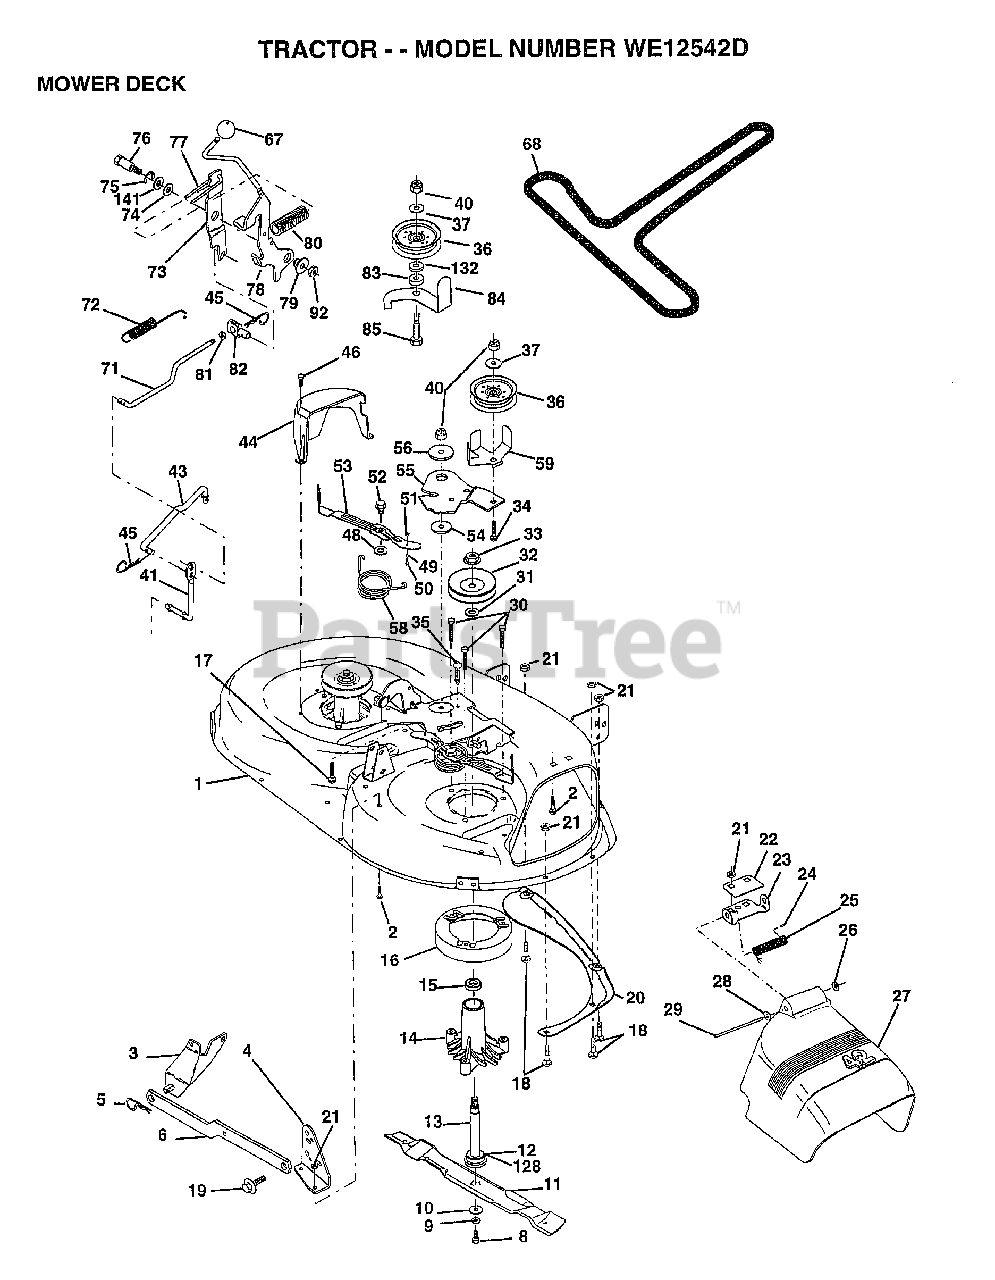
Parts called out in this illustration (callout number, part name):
1	"HOUSING ASSY.42"""
2	BOLT
3	BRKT ASM SWAY BAR
4	BRKT DECK SW BAR
8	BLADE BOLT
10	WASHER.HARD.BLADE
11	"BLADE.42"" HIPERF"
12	BEARING.BALL
14	HSG ASM MANDREL
15	BEARING
16	STRIPPER RND MWR
17	BOLT RDHD 3/8-16
18	BOLT
19	BOLT SHD 5/16-18
20	BAFFLE VORTEX 42
22	STIFFENER BRKT
23	DEFLECTOR BRKT
24	CAP-SLEEVE LT
25	SPRING TORSION
26	NUT PUSH M
27	DEFLECTOR.SHIELD
28	WASHER
29	HINGE ROD
30	"SCREW-THD ROLL,WA"
31	WASHER
32	PULLEY.MANDREL.42
34	BOLT
35	XMAS TREE FASTNER
36	FLAT IDLER PULLEY
37	WASHER
41	PIVOT ROD
43	ROD CLUTCH W/NIBS
44	GUARD MAND LH BLK
45	RETAINER M
46	SCREW.1/4-20X5/8
48	HARD SMALL WASHER
49	ROLLER ASM-CAM
50	SHOULDER BOLT
51	LOCKNUT
52	BOLT.SHLD.5/16-18
53	BRAKE PAD ARM ASM
54	HARDENED WASHER
55	ARM-IDLER
56	SPACER RETAINER
58	SPRING TORSN BRAK
59	GUARD IDLER TUV
67	KNOB.RD.7/16-14
68	BELT.V.T-PATH
71	ROD CLUTCH 38/42
72	RETURN SPRING
73	CLUTCH ARM SECOND
74	WASHER
75	RING
76	SHOULDER BOLT
77	SPRING KEEPER
78	LEVER.ASM.CLUTCH
79	BUSHING
80	SPRING.CLUTCH.MWR
81	NUT
82	TRUNION ADJ
83	WASHER
84	"KEEPER-BELT,FIXED"
85	BOLT
92	NUT
128	WASHER.FELT.
132	WASHER GT
141	WASHER .T
